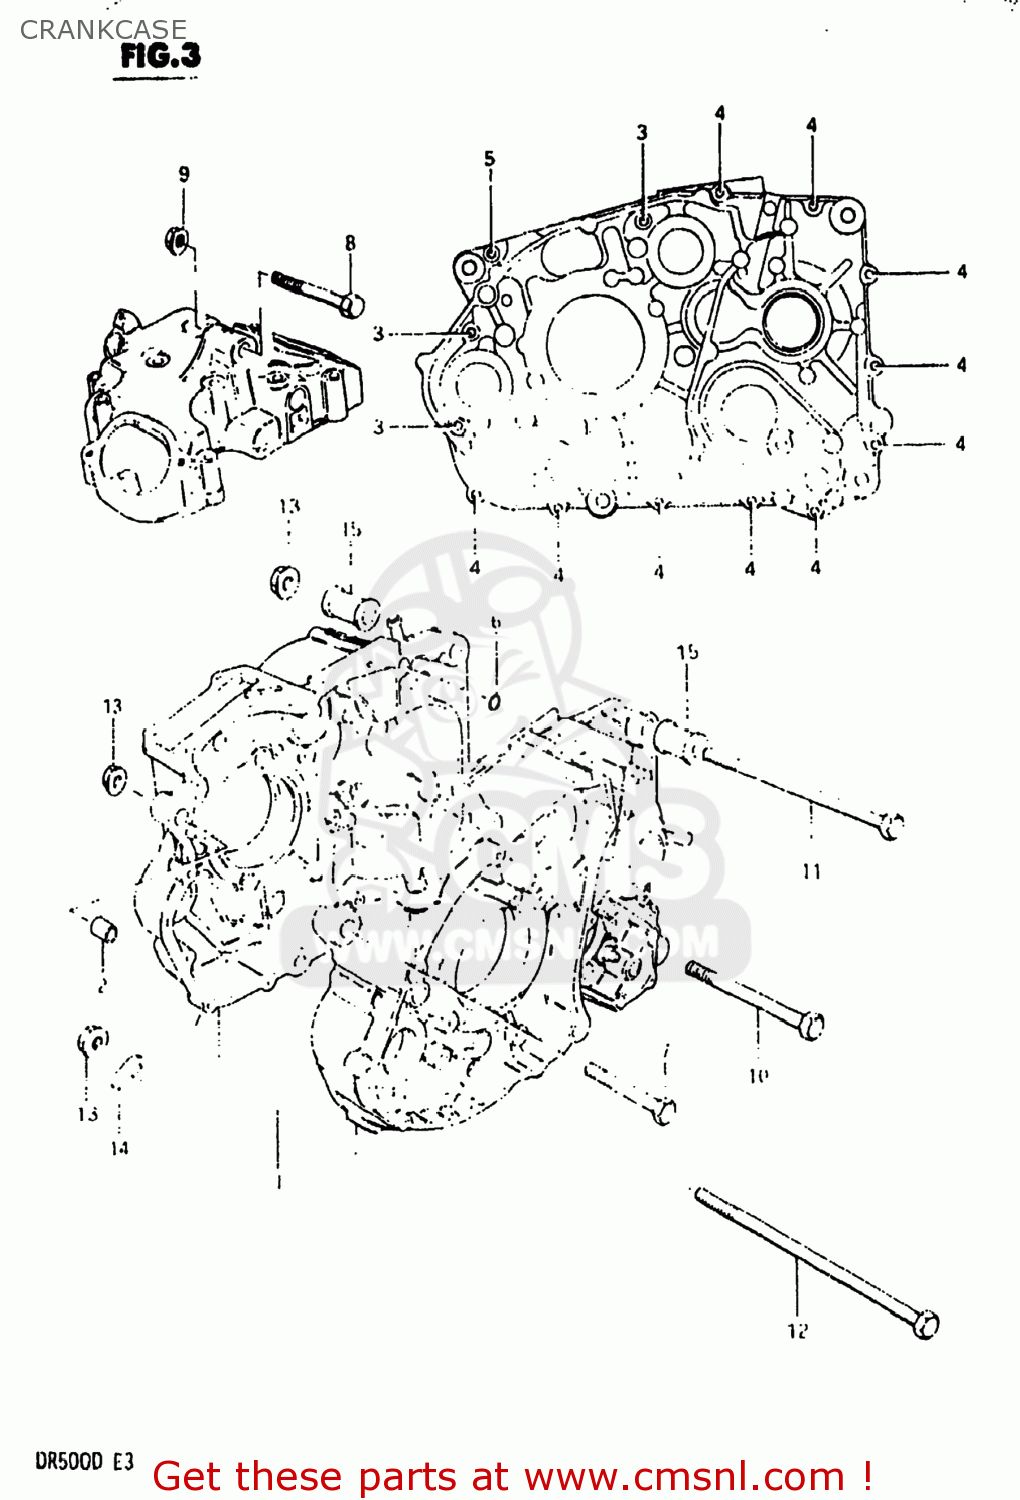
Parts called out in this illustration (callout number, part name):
1	CRANKCASE ASSEMBLY
2	PIN
3	BOLT (6X60)
4	BOLT (6X40)
5	BOLT (6*30)
6	O-RING
7	BOLT 10X70
8	BOLT (8X50)
9	NUT
10	BOLT(10X120)
11	BOLT(10X180)
12	BOLT
13	NUT 10MM
14	WASHER
15	SPACER,ENGINE MOUNT
